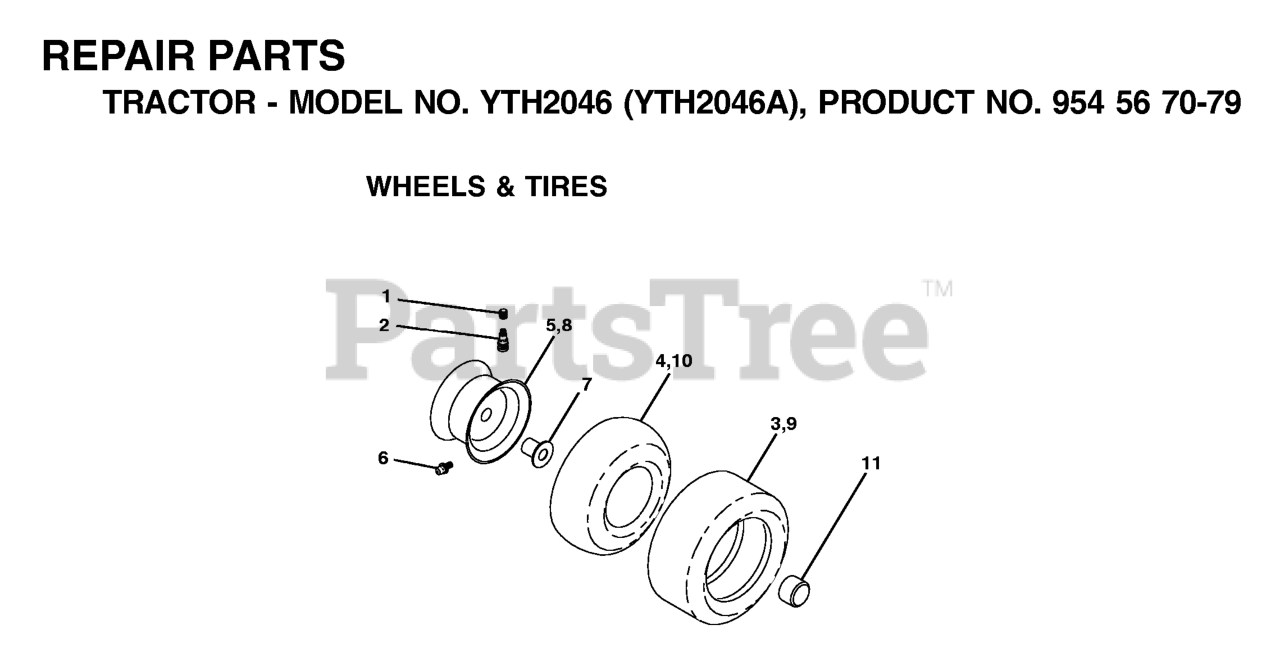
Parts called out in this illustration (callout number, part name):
2	VALVE STEM LT
3	TIRE HEAVY DUTY
4	TUBE.5.3/4.5/6
5	RIM ASM 6" FRONT SILVER
6	FITTING LT
7	BEARING T
8	RIM ASM 8" REAR SILVER
9	TIRE.TS.20X10-8
10	TUBE
11	CAP, AXLE BLK
